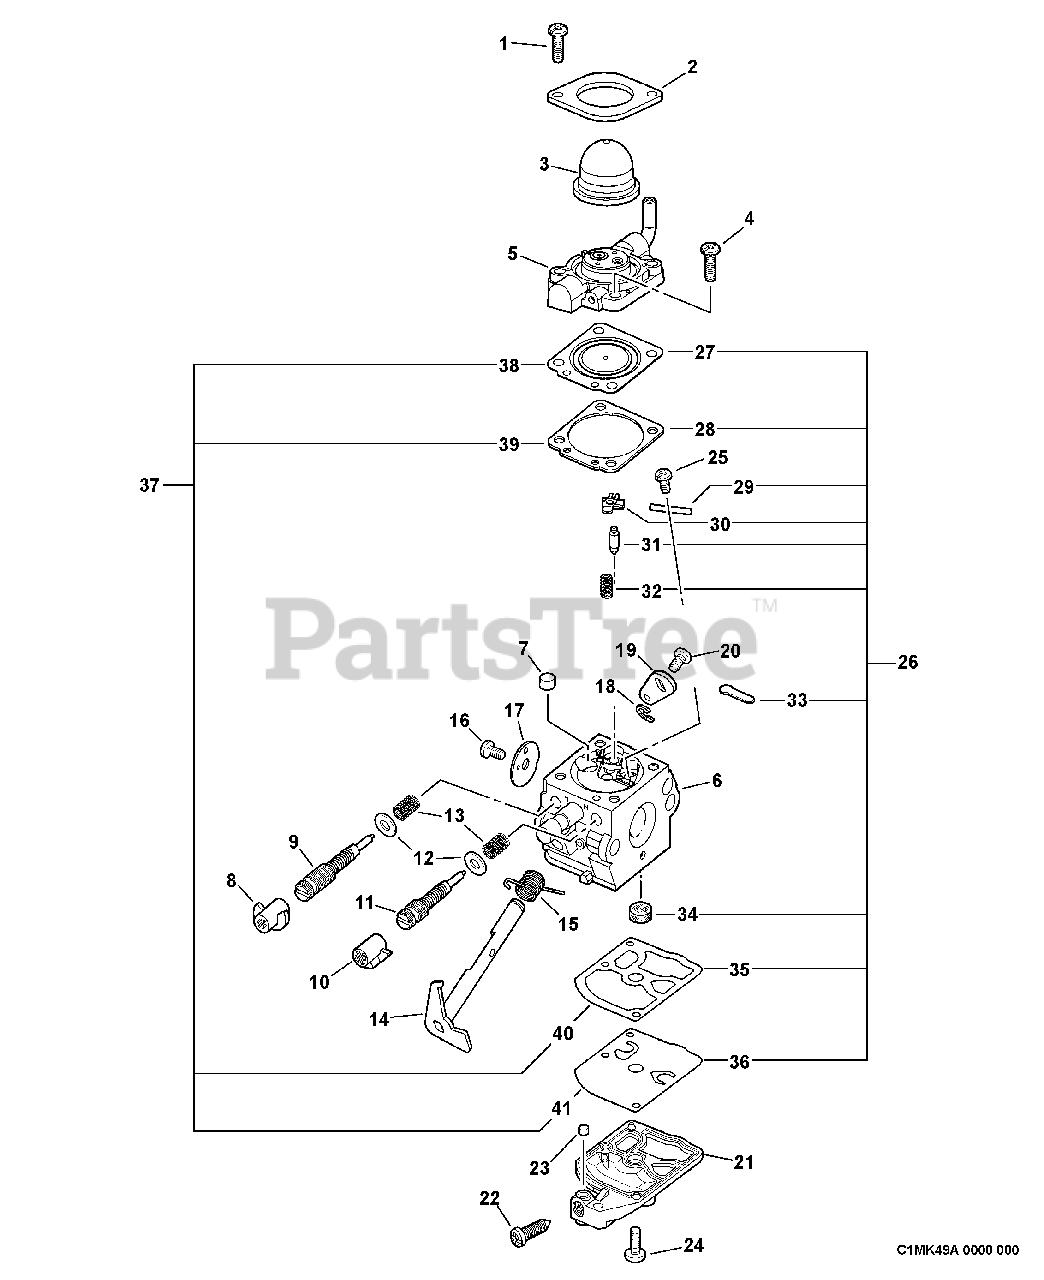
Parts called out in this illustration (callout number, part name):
1	SCREW, RETAINER
2	RETAINER, PURGE BULB
3	BULB, PURGE
4	SCREW, PURGE BASE
5	BASE, PURGE
6	BODY, CARBURETOR
7	NOZZLE, CHECK VALVE
8	CAP, LIMITER
9	NEEDLE - LOW SPEED
10	CAP, LIMITER
11	NEEDLE - HIGH SPEED
14	SHAFT, THROTTLE
15	SPRING, TRIGGER
17	VALVE, THROTTLE
18	RING, RETAINING
19	LEVER, THROTTLE
21	COVER, FUEL PUMP
22	SCREW, IDLE ADJUST
23	PIECE, FRICTION
24	SCREW, PUMP COVER
25	SCREW, METERING LEVER PIN
26	REPAIR KIT
27	DIAPHRAGM, METERING
28	GASKET, DIAPHRAGM
29	PIN, METERING LEVER
30	LEVER, METERING
31	VALVE, INLET NEEDLE
32	SPRING, METERING LEVER
33	PLUG, WELCH
34	STRAINER
35	GASKET, PUMP
36	DIAPHRAGM, PUMP
37	DIAPHRAGM/GASKET KIT
38	DIAPHRAGM, METERING
39	GASKET, DIAPHRAGM
40	GASKET, PUMP
41	DIAPHRAGM, PUMP
